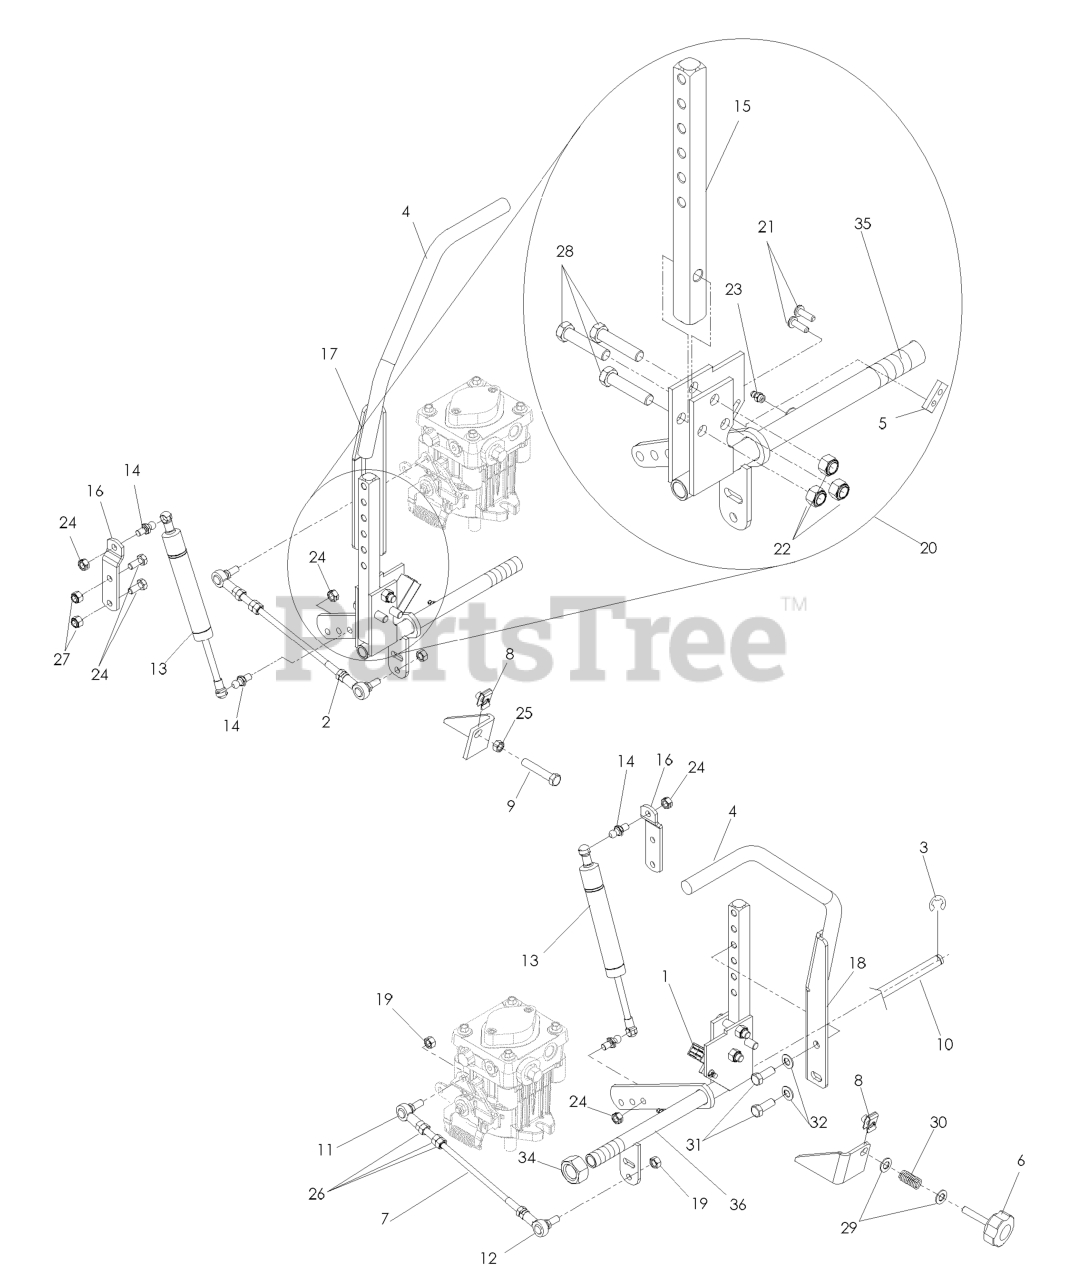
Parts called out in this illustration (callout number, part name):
1	SWITCH, INTERLOCK
2	NUT 5/16F LEFTHAND
3	E-RING 1/2 (2 2)
4	GRIP - DRIVE LEVER 12"
5	TAPPED PLATE
6	ADJUSTMENT KNOB
7	PUMP CONTROL LINK
8	U-CLIP 5/16-18 NUT RETAINER
9	HCS 5/16-18X1-3/4 TPBLT
10	CONTROL SHAFT
11	SPHERICAL ROD END, RH
12	SPHERICAL ROD END, LH
13	DAMPENER W/EXT SEAL
14	STUD.BALL.10MM
15	CONTROL ARM
16	DAMPENER ARM
17	ASSEMBLY, DRIVE LEVER RT
18	ASSEMBLY, DRIVE LEVER LT
19	NUT 5/16F NYLOC
20	CONTROL ASM, RT
20	CONTROL ASM, LT
21	SCREW #10-24 X 5/8
22	NUT 3/8-16 NYLOC
23	ZERK
24	NUT 5/16C CENTERLOCK
25	NUT 5/16C HEX
27	NUT 5/16 NYLOC
28	HCS 3/8-16 X 1 3/4 GR5
29	WASHER 5/16 FLAT
30	COMPRESSION SPRING
31	HCS 3/8-16X1.GRD.5.ZD
32	WASHER, 3/8 DISC SPRING SPEC
33	HCS 5/16C X 3/4
34	NUT 3/4 X 16 HEX CTR
35	DRIVE CONTROL, RT
36	DRIVE CONTROL, LT
